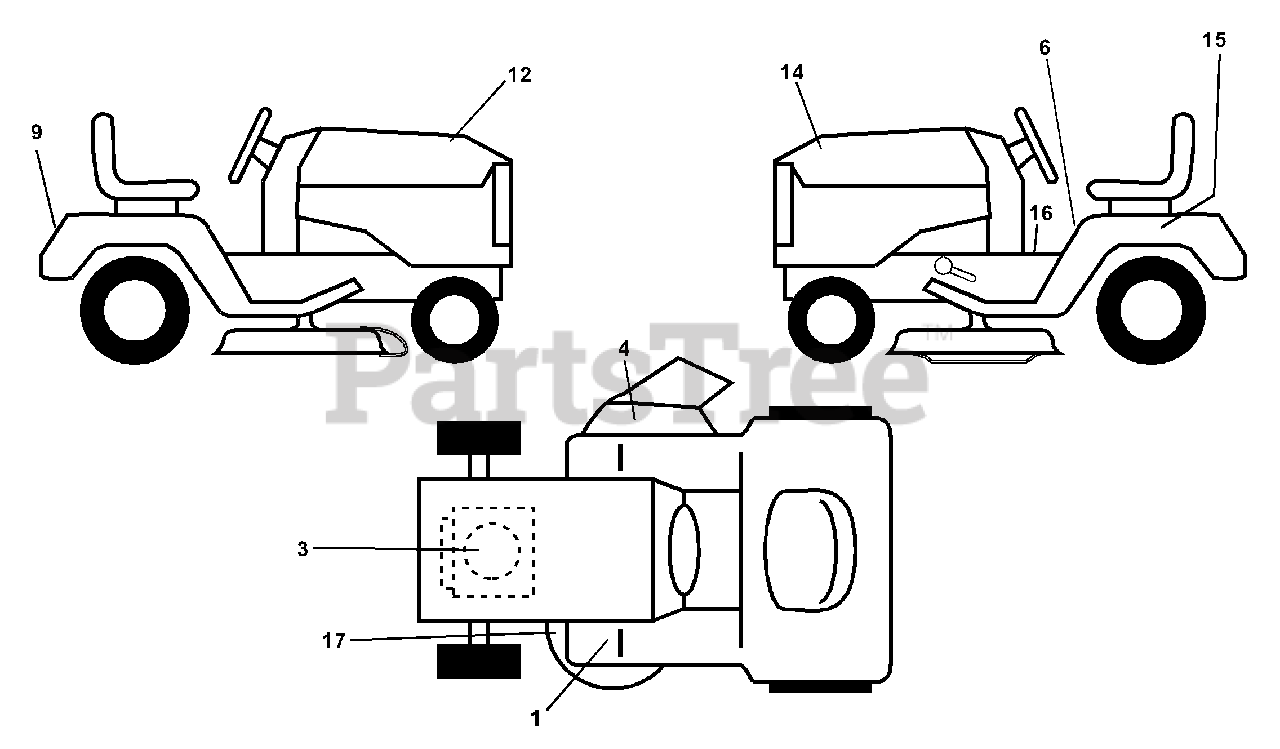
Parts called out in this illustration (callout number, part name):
1	Decal, Clutch/Brake Eng/Fr
3	Decal, Engine HP
4	Decal Warning
6	Decal, Fender Danger English
9	Decal Fender
12	Decal, Hood RH
14	Decal, Hood LH
15	Decal, Caution, Battery
16	Decal, Oper Sdl P/L Gear Dr Eng
17	Decal, V-Belt Sch.
